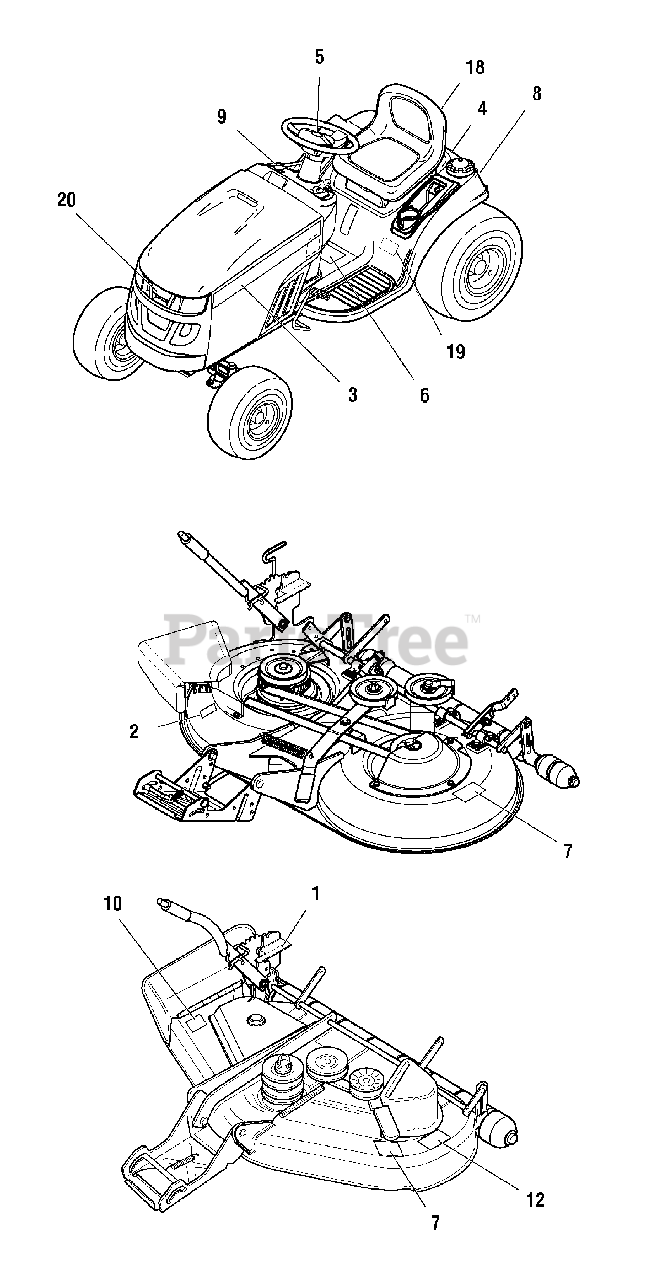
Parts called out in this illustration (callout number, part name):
2	DECAL, Cut, 42
3	DECAL, Stripe, Allis Chalmers, With Logo
4	DECAL, Allis Chalmers, Rear
5	DECAL, Steering Wheel
6	DECAL, Tunnel
7	DECAL, Danger, Hands / Feet
8	DECAL, Transmission Tow, Release Lever
9	DECAL, Ignition Switch
10	DECAL, Danger Do Not Operate Without Deflector
12	DECAL, Cut, 46 Inch
18	DECAL, Allis Chalmers Logo
19	DECAL, Model, 23HP
19	DECAL, Model, 24HP
20	DECAL, Allis Chalmers, Logo, LT125
